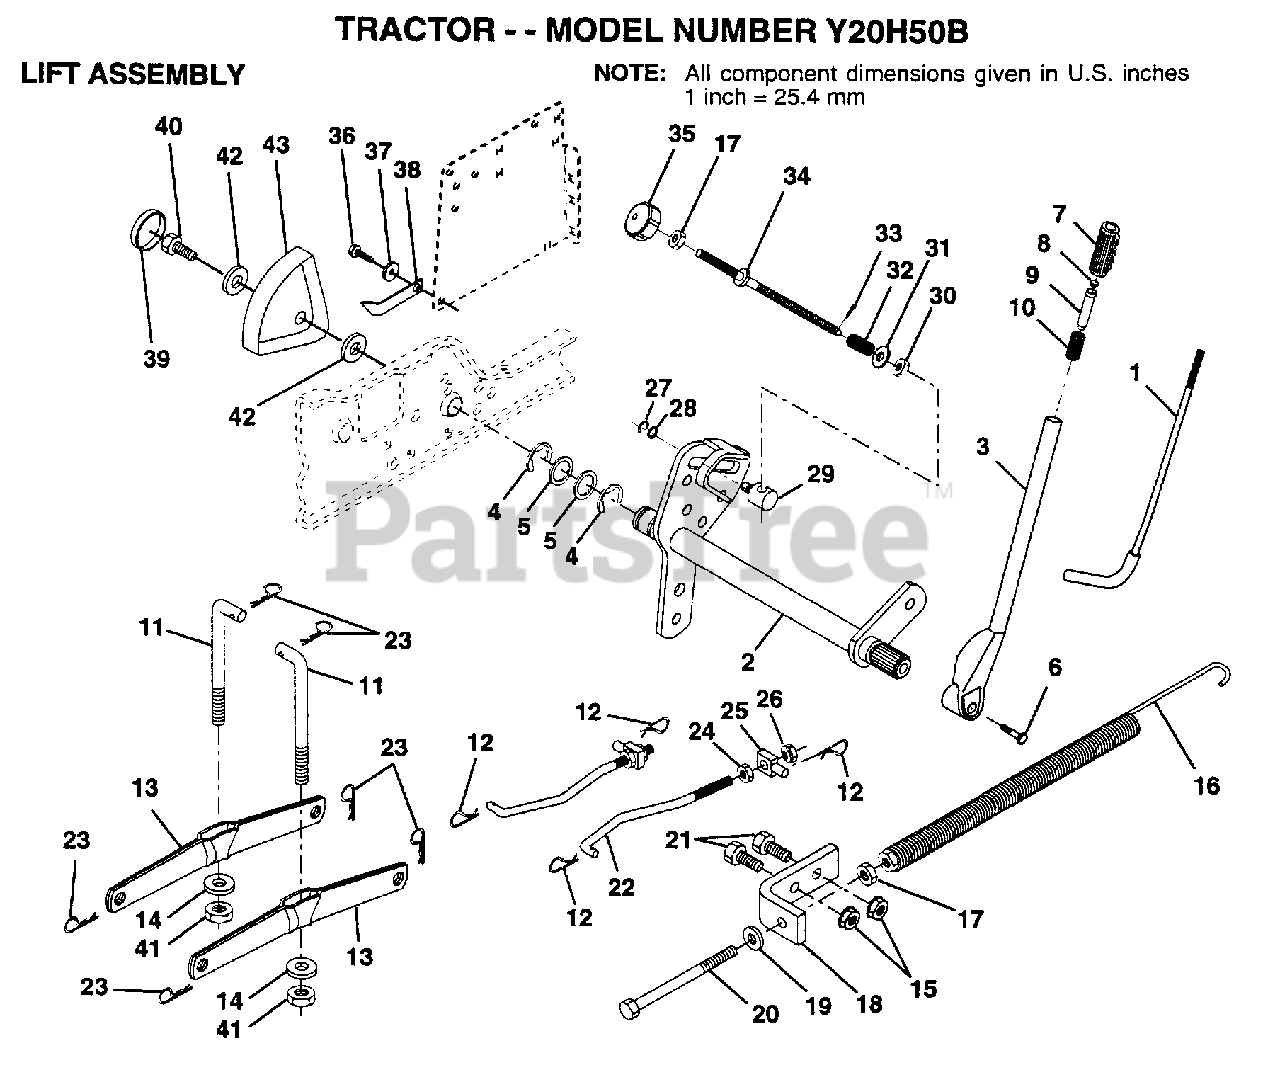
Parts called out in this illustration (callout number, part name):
1	LEVER ROD LT (2 2)
2	SHAFT.LIFT.VGT.95
4	E-RING
5	WASHER
6	"BOLT,HEX"
7	GRIP HANDLE
8	Button Plunger Black
10	SPRING T
11	LINK.LIFT.MWR.VGT
12	RETAINER.SPRING
13	ARM SUSP REAR
14	BEARING PVT LH
16	SPRING ASS'Y
17	NUT
18	BRACKET SPRING AS
19	WASHER
20	BOLT-ADJ SPRING T
21	BOLT
22	LINK.FRONT
24	NUT
25	TRUNION
26	NUT.LK.W/WSH.1/2.
27	KLIP RING
28	WASHER
29	TRUNION LT
30	NUT T (2 2) (1 2)
31	WASHER
32	SPRING.COMP.INF.H
34	ROD.ADJ.LIFT
35	KNOB INF 3/8-16
36	SCREW
37	No Desciption for Part
38	POINTER HGT IND
39	PLUG,HOLE
40	SCREW THDROL 516-18 X 3/4 TYT
41	NUT.CROWNLOCK.3/8
42	WASHER
43	HEIGHT INDICATOR
